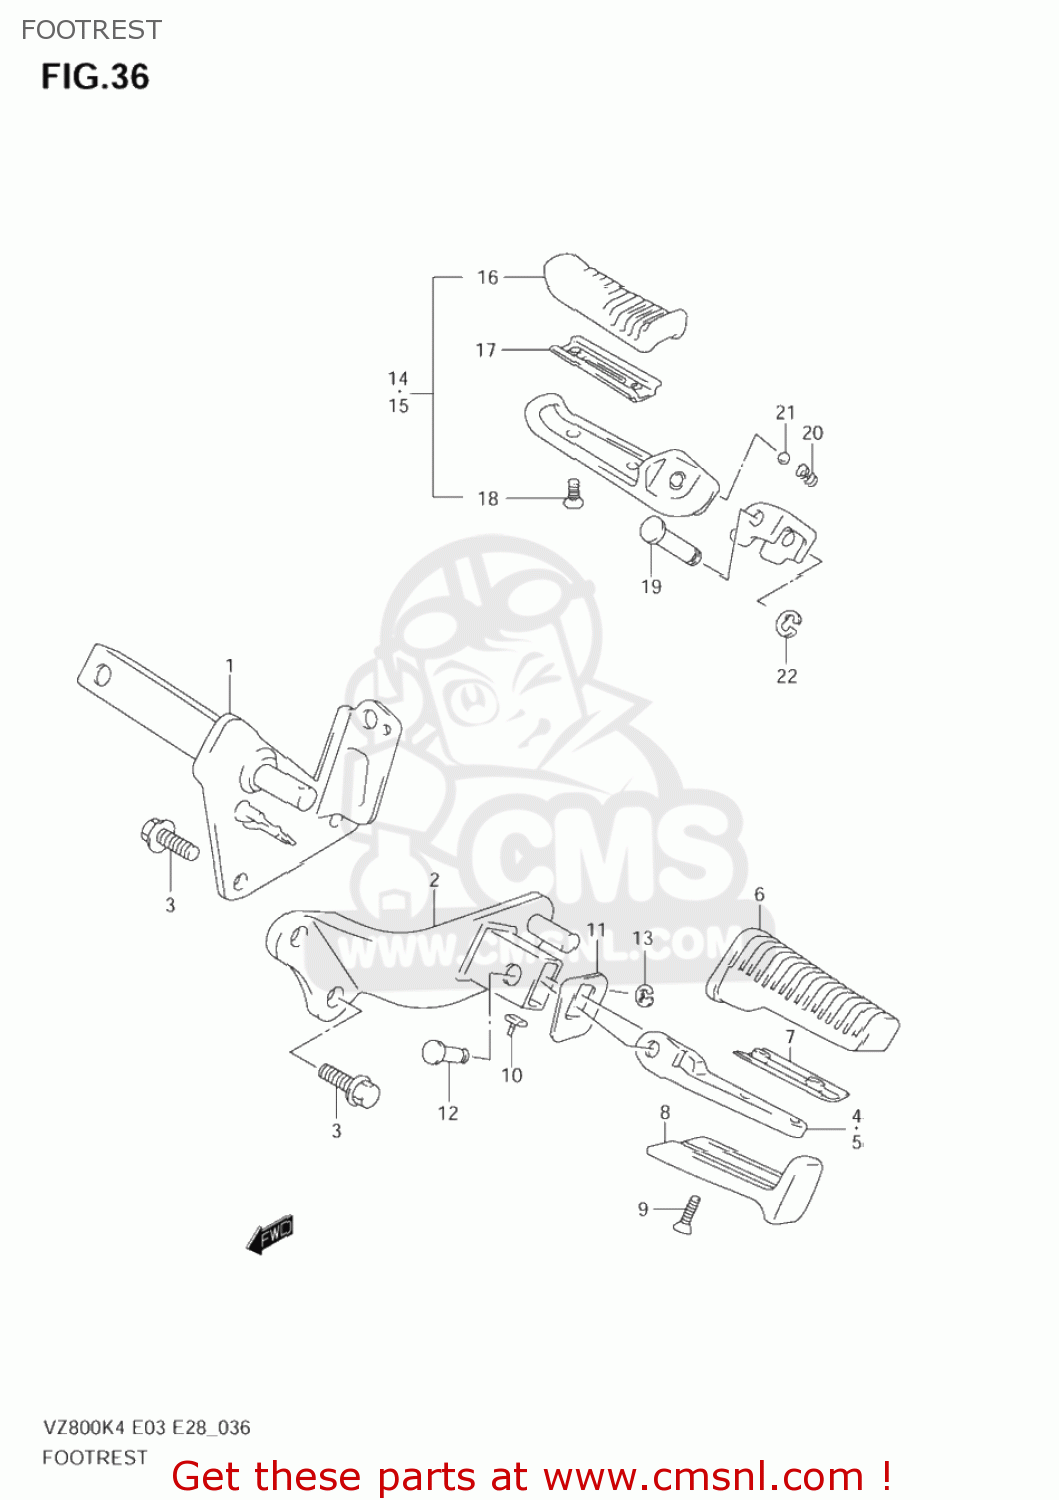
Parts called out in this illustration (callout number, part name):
1	BRACKET,FR FOOTREST,R
2	BRACKET,FR FOOTREST,L
3	BOLT
4	BAR,FR FOOTREST,R
5	BAR,FR FOOTREST,L
6	RUBBER,FR FOOTREST
7	PLATE,RUBBER STOPPER
8	COVER,FR FOOTREST
9	SCREW(5X20)
10	CUSHION,FR FOOTREST BAR
11	WASHER,FR FOOTREST
12	PIN
13	E.RING
14	FOOTREST ASSY,PILLION,R
15	FOOTREST ASSY,PILLION,L
16	RUBBER,PILLION FOOTREST
17	PLATE,RUBBER STOPPER
18	SCREW(5X16)
19	PIN
20	SPRING
21	BALL
22	E.RING
